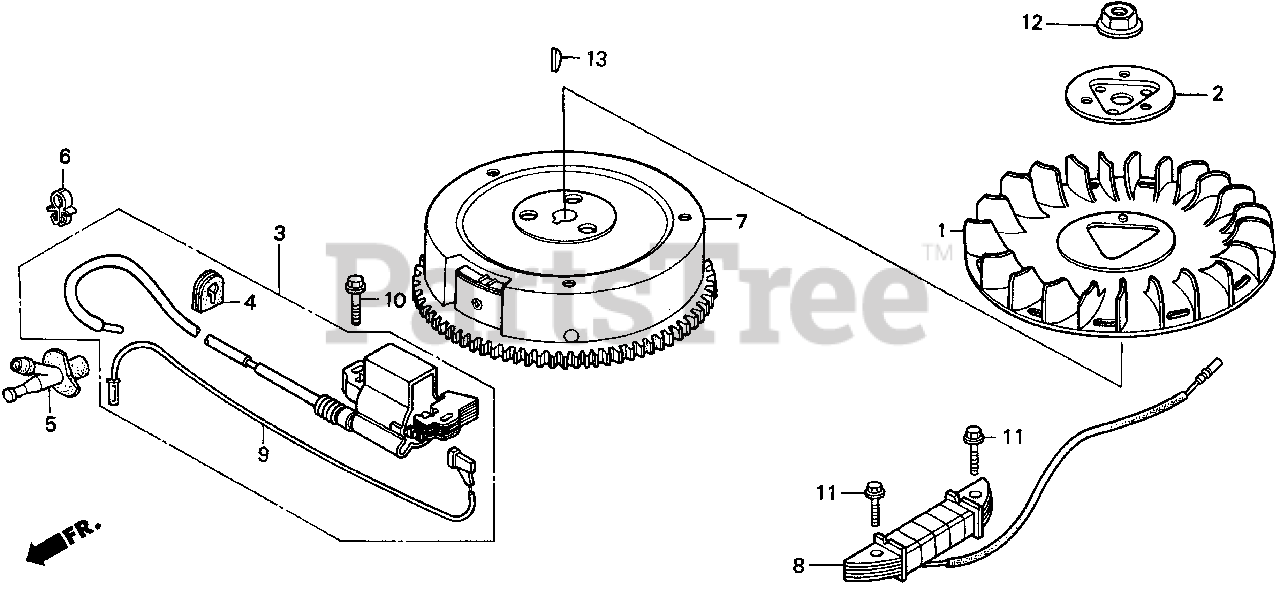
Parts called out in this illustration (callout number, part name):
1	FAN, COOLING
2	PLATE, COOLING FAN SETTING
3	COIL ASSY., IGNITION
4	GROMMET, IGNITION
5	CAP ASSY., NOISE SUPPRESSOR
6	CLIP, IGNITION WIRE (8MM)
7	FLYWHEEL
8	COIL ASSY., CHARGE (3A)
9	WIRE, STOP SWITCH
9	WIRE, STOP SWITCH (NOT AVAILABLE)
10	BOLT, FLANGE (6X28) (CT200) Use up to Engine SN 1530314.
11	BOLT, FLANGE (6X32)
12	NUT, SPECIAL (16MM) (1)
12	NUT, SPECIAL (16MM)
13	KEY, SPECIAL WOODRUFF (25X18)
